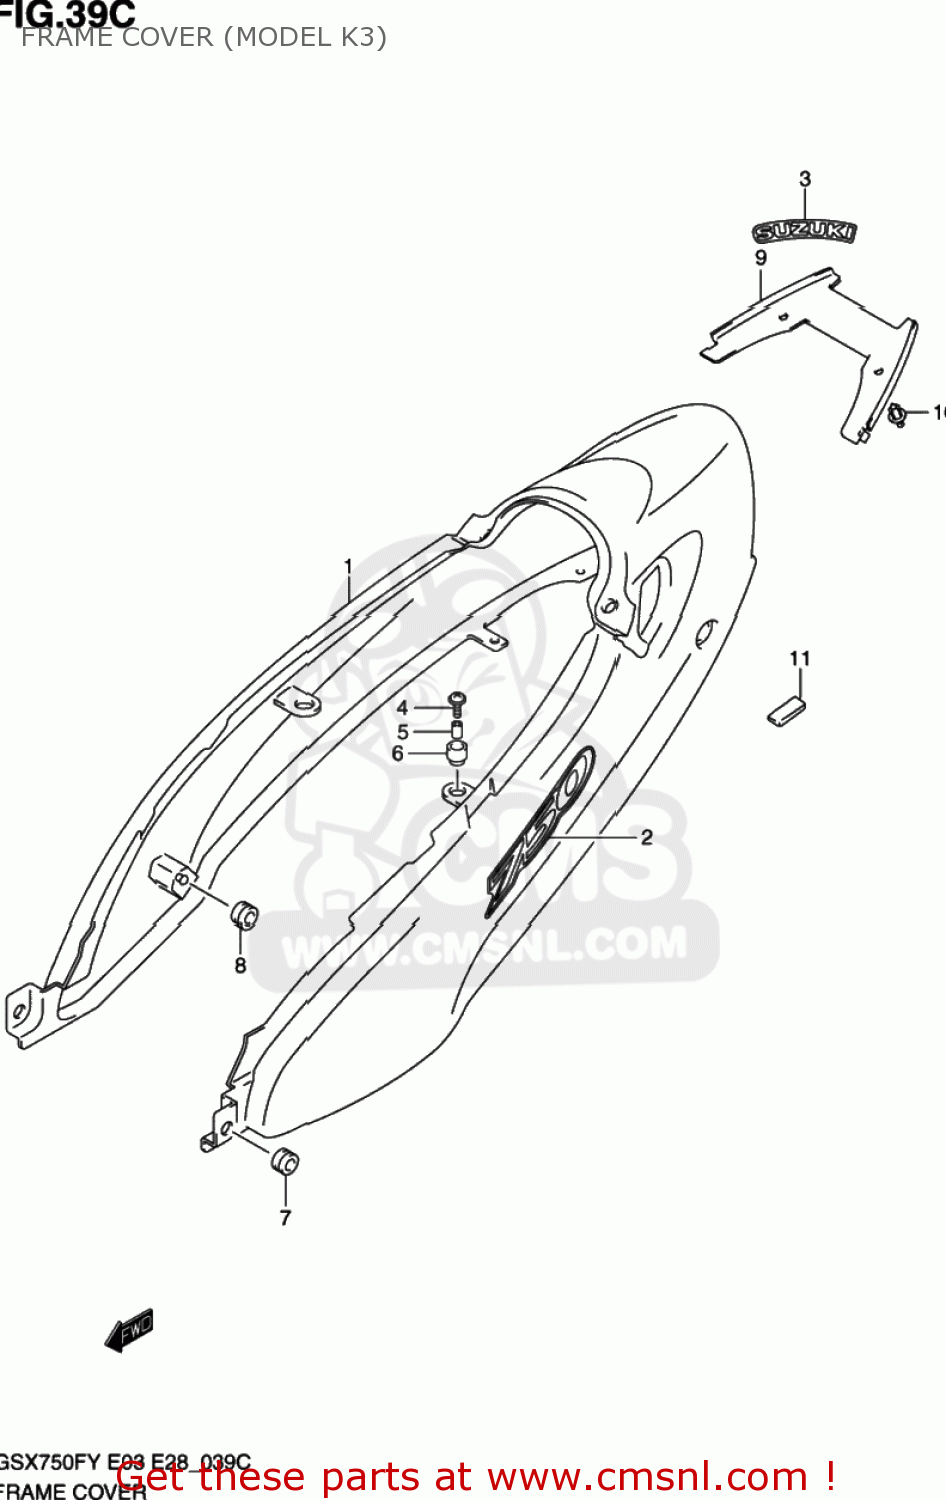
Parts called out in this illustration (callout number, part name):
1	COVER,FRAME(BLACK)
2	EMBLEM,FRAME COVER
3	EMBLEM,SUZUKI
4	SCREW(6X20)
5	SPACER(6.5X10X9.4)
6	CUSHION
7	CUSHION
8	CUSHION
9	COVER,FRAME LWR
10	CLIP(BLACK)
11	CUSHION
